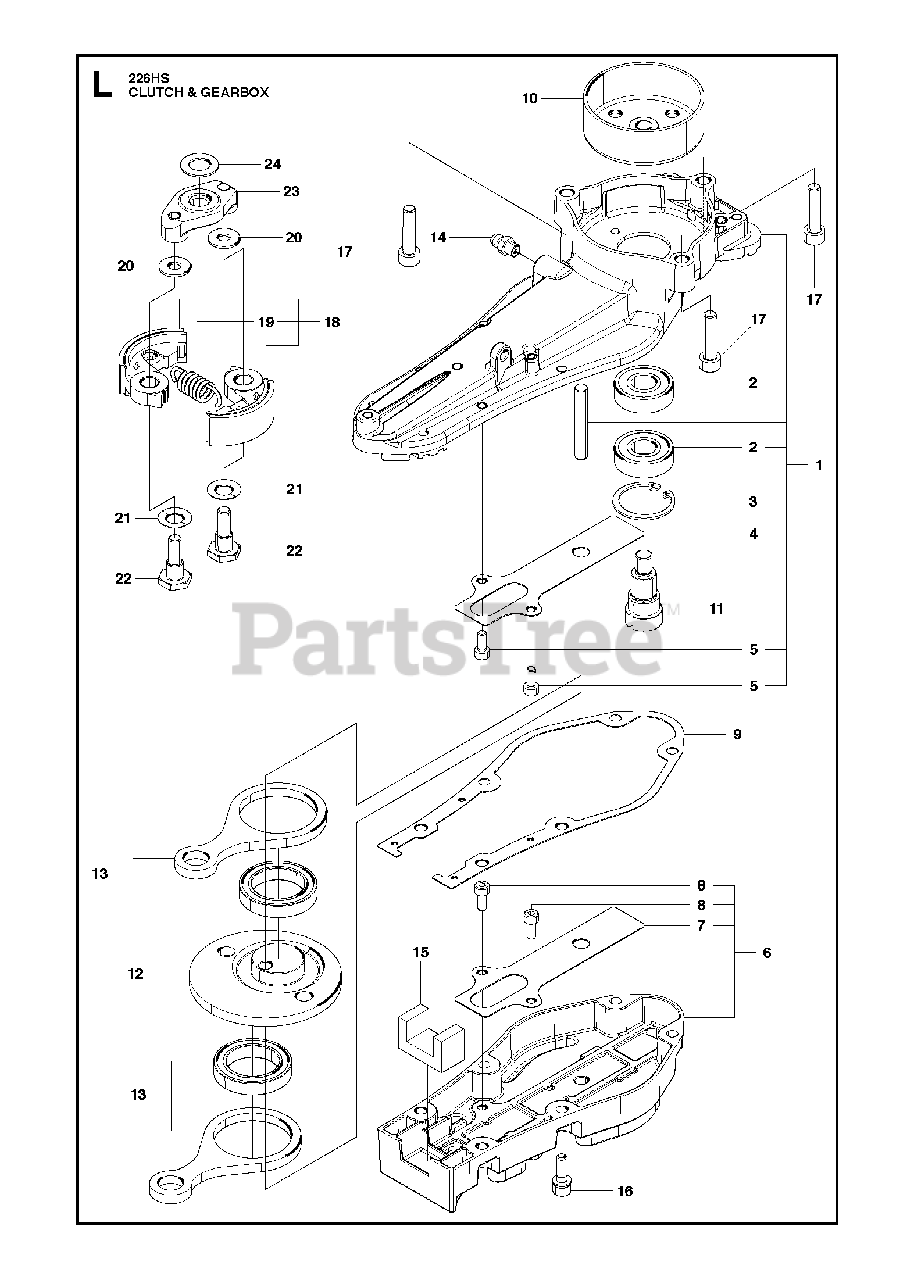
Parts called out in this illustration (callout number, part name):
1	GEARCASE COMPLETE UPPER
2	BEARING
3	RING
4	PLATE
5	BOLT
6	GEARCASE COMP. BOTTOM
7	PLATE
8	BOLT
11	GEAR DRIVE
12	GEAR DRIVE
19	SPRING
23	PLATE CLUTCH
